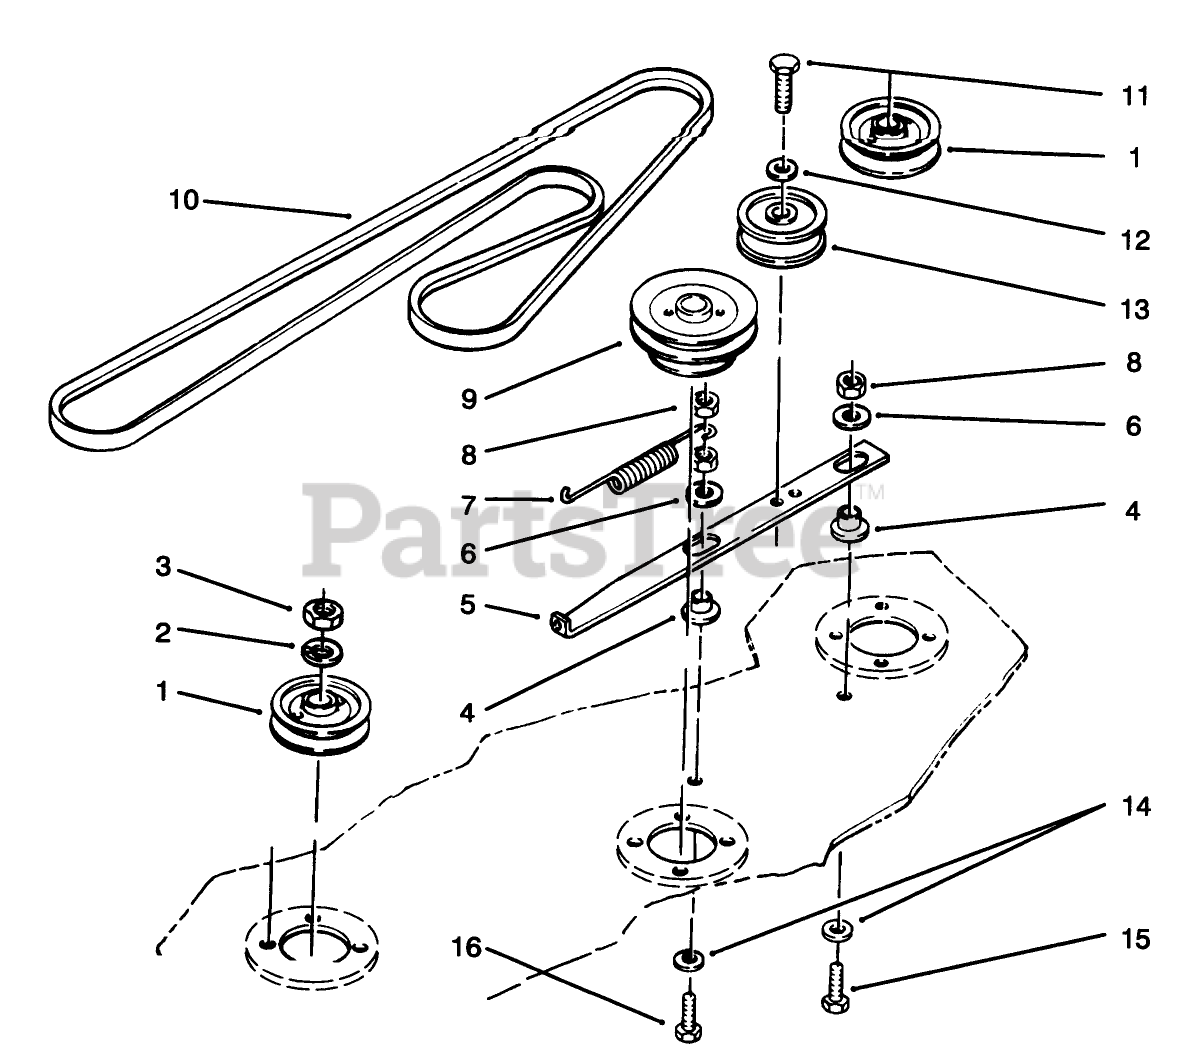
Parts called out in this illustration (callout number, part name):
1	PULLEY
2	WASHER-LOCK
3	NUT-JAM
4	SPACER-BUSHING
5	BAR-IDLER SUPPORT
6	WASHER
7	SPRING-EXTENSION
8	NUT-LOCK, NI
9	PULLEY
10	V-BELT
11	SCREW-HH
12	WASHER-LOCK
13	PULLEY-IDLER, FLAT
14	WASHER
15	SCREW-HH
16	SCREW-HH
